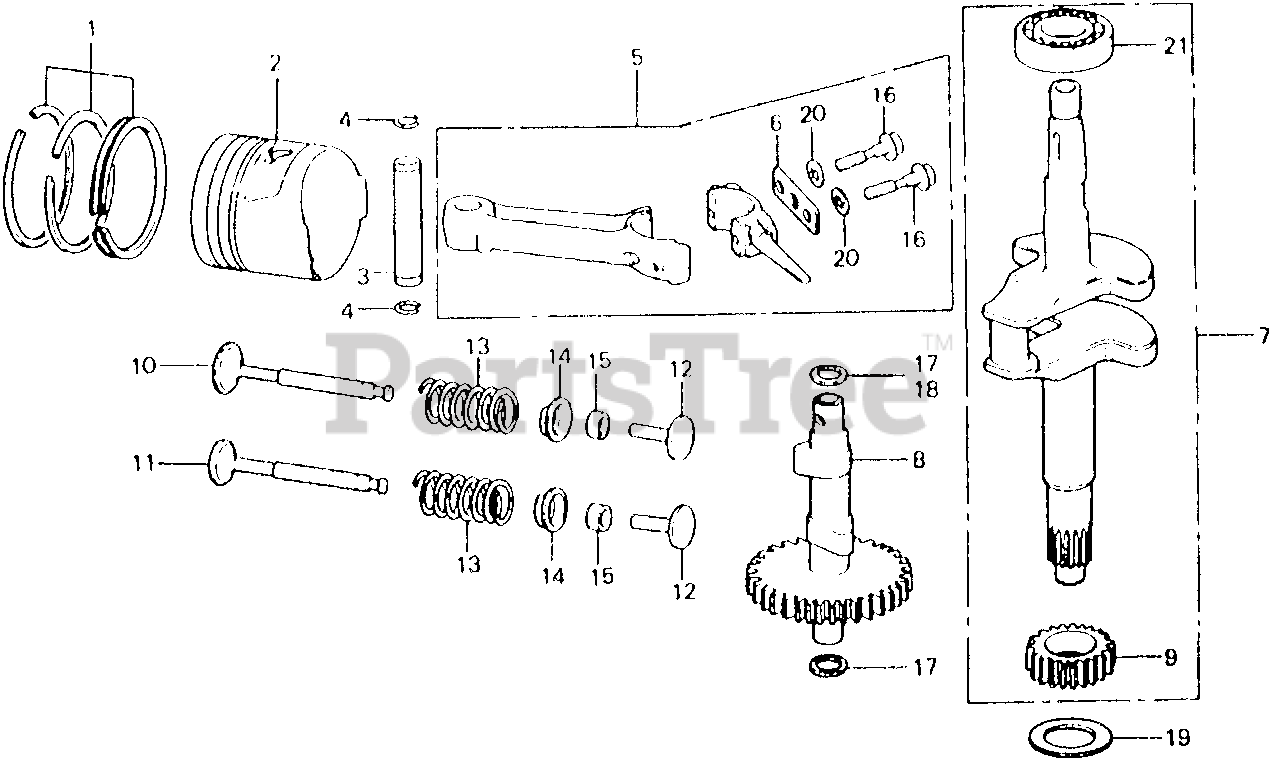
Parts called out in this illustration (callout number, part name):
1	RING SET, PISTON (STD)
1	RING SET, PISTON (OS 0.25)
1	RING SET, PISTON (OS 0.50)
1	RING SET, PISTON (0.75)
2	PISTON
2	PISTON (STD)
2	PISTON (OS 0.25)
2	PISTON (OS 0.50)
2	PISTON (0.75)
3	PIN, PISTON
4	CLIP, PISTON PIN (10MM)
5	ROD ASSY., CONNECTING (STD)
5	ROD ASSY., CONNECTING
5	ROD ASSY., CONNECTING Use up to Engine SN 1443595.
6	WASHER, CONNECTING ROD (NOT AVAILABLE)
7	CRANKSHAFT (NOT AVAILABLE)
9	GEAR, TIMING
10	VALVE, IN.
11	VALVE, EX.
12	LIFTER, VALVE
13	SPRING, VALVE
14	RETAINER, VALVE SPRING
15	ADJUSTER, TAPPET CLEARANCE
16	BOLT, CONNECTING ROD
17	WASHER (10MM)
18	WASHER, THRUST (9.9MM)
19	WASHER, THRUST (20X1.00)
20	WASHER, LOCK
21	BEARING, RADIAL BALL (6203)
